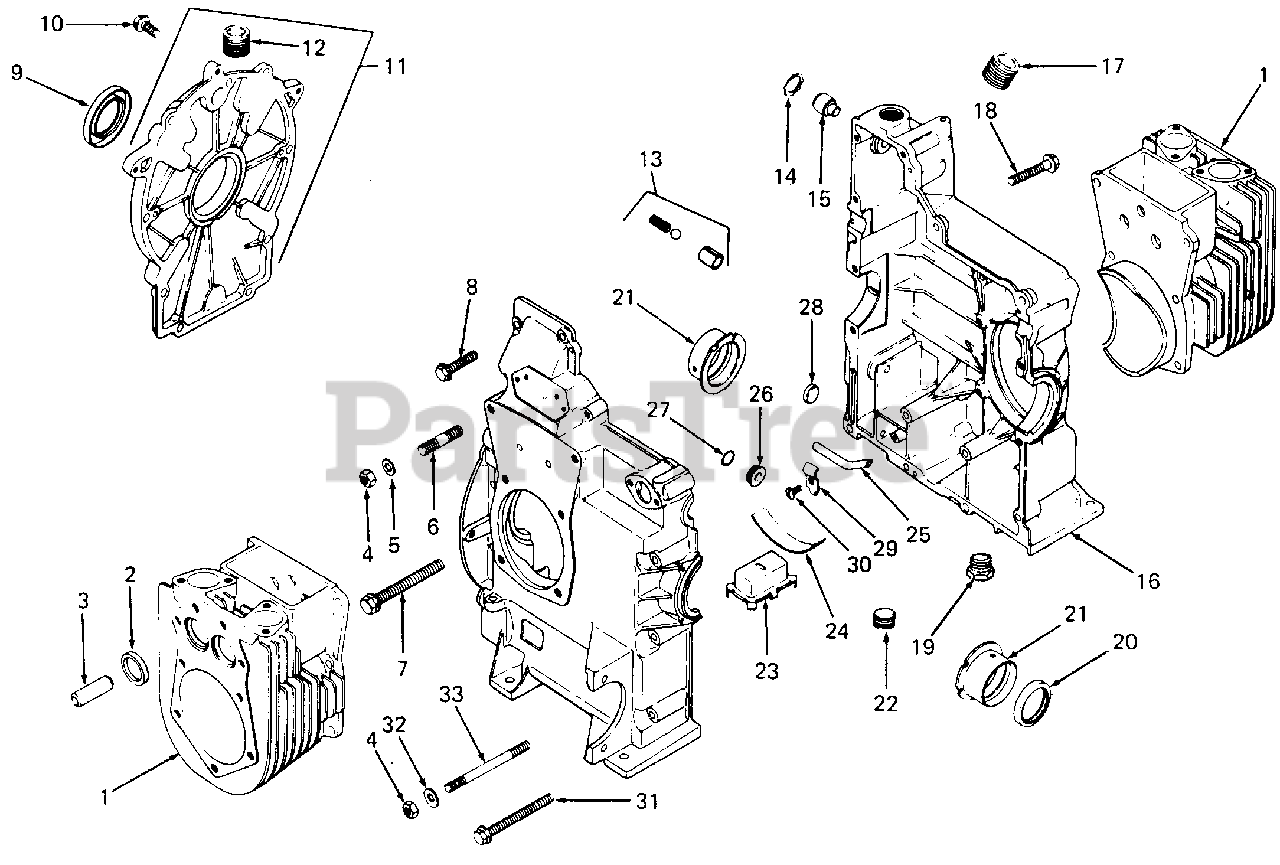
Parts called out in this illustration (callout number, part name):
1	Kit, Cylinder Barrel
2	Insert, Valve Seat
3	Guide, Valve
4	Nut, Hex, 5/16-18
5	Washer, Flat
6	Stud, Step, 5/16-18 X .75, 3/8-16 X .62, 2.0 Lg
7	Screw, Hex Flange, 3/8-16 X 3.62 Lg
8	Screw, Hex Flange, 5/16-18 X 1.5 Lg
9	Seal, Rear Oil
10	Screw, Wash Hd, 5/16-18 X 1.0 Lg
11	Kit, Closure Plate
12	Plug, Hex Ctsk, 1/8 NPTF
13	Kit, Oil Relief
14	Ring, Retaining
15	Shaft, Governor
16	Crankcase
17	Plug, Pipe, 1/16 X 27 NPTF
18	Screw, Hex Flange, 5/16-18 X 2.0 Lg
19	Plug, Bottom Drain, 3/8
20	Seal, Front Oil
21	Bearing, Sleeve (Std)
22	Plug, Hex Ctsk, 3/8 NPTF
23	Housing, Oil Pickup
24	Clamp, Spring
25	Tube, Oil Pickup
26	Plug, 3/4 OD
28	Plug, Cup, 5/16
30	Screw, Hex Wash Hd, #10-32 X 7/16 Lg
31	Screw, Hex Flange, 5/16-18 X 3.5 Lg
32	Washer, Plain
33	Stud, 5/16-18 X 4.12 Lg
